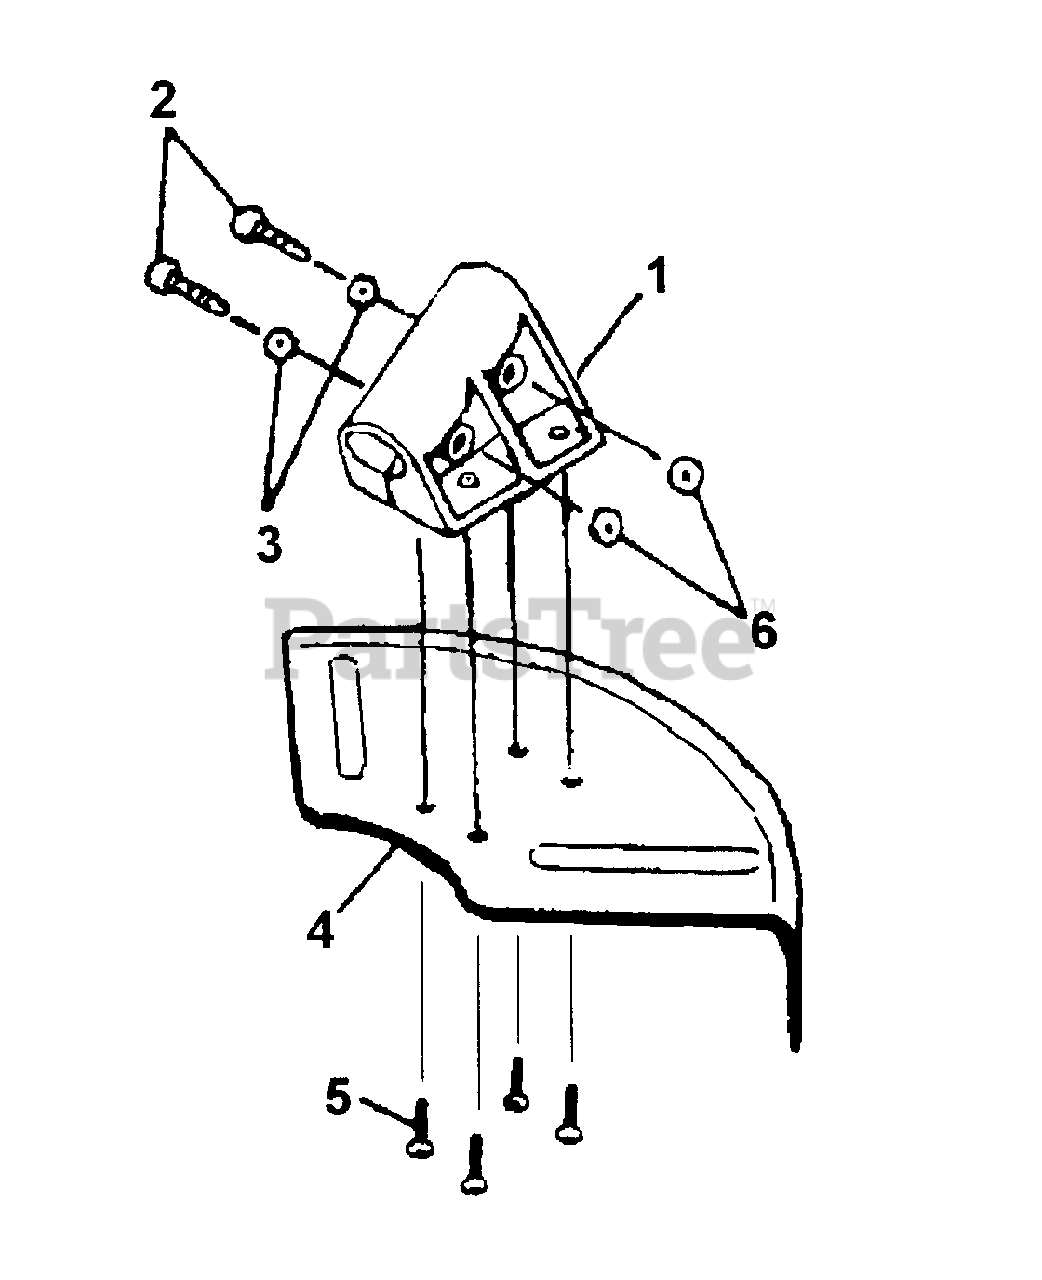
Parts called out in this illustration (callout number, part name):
1	BRACKET, BLADE GUARD
2	SCREW
4	GUARD
5	SCREW
